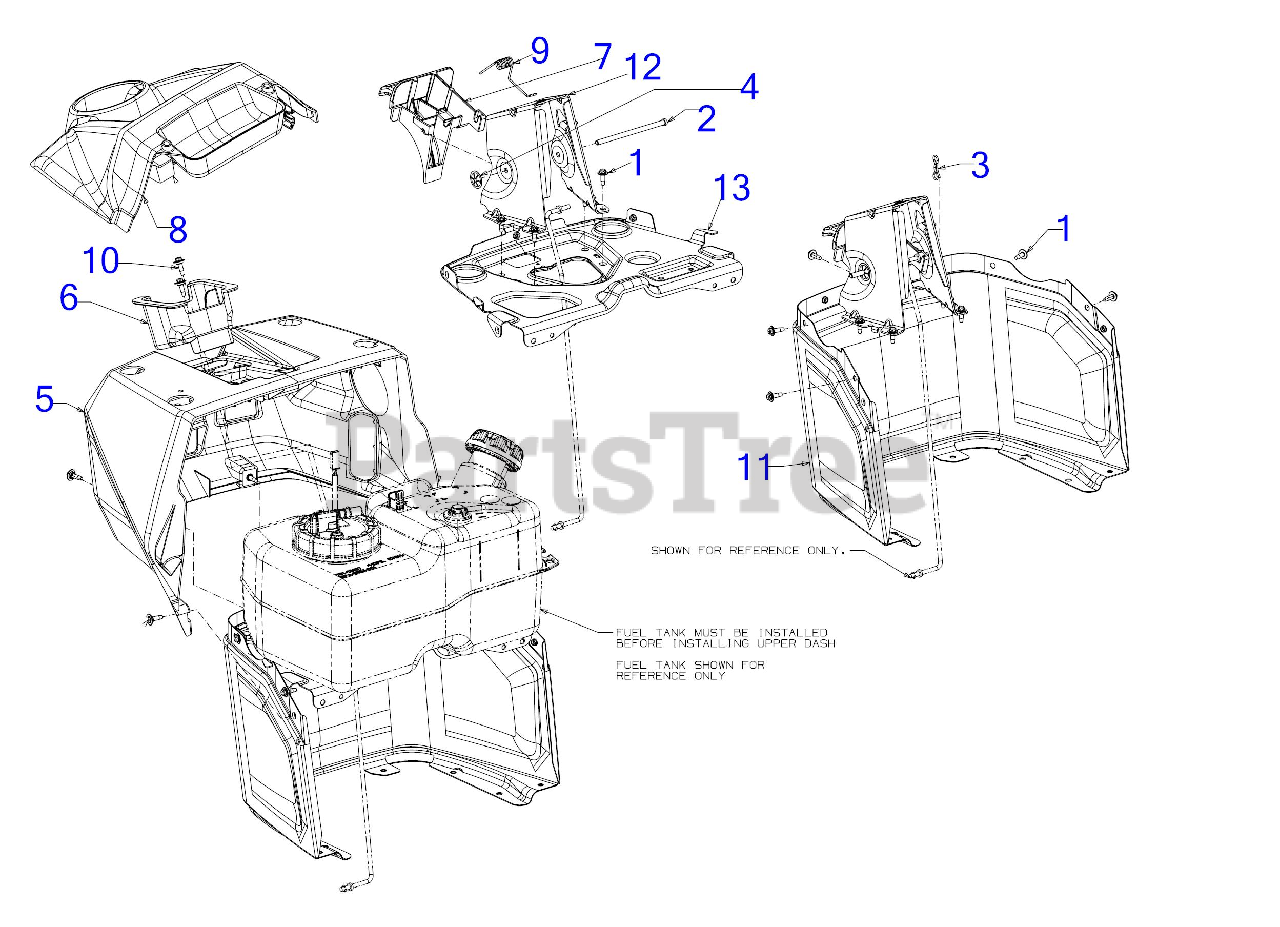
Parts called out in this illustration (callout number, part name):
1	SCREW M6-1 x .625
2	HINGE PIN .25 x 4.50
3	BOW TIE COTTER PIN 1/4-5/16
4	PUSH ON NUT
5	UPPER DASH
6	STEERING SHAFT BEARING
7	CRUISE/BRAKE DASH LEVER
8	UPPER DASH CAP
9	TORSION SPRING .330 ID
10	SHOULDER SCREW M6-1 .368 X.115
